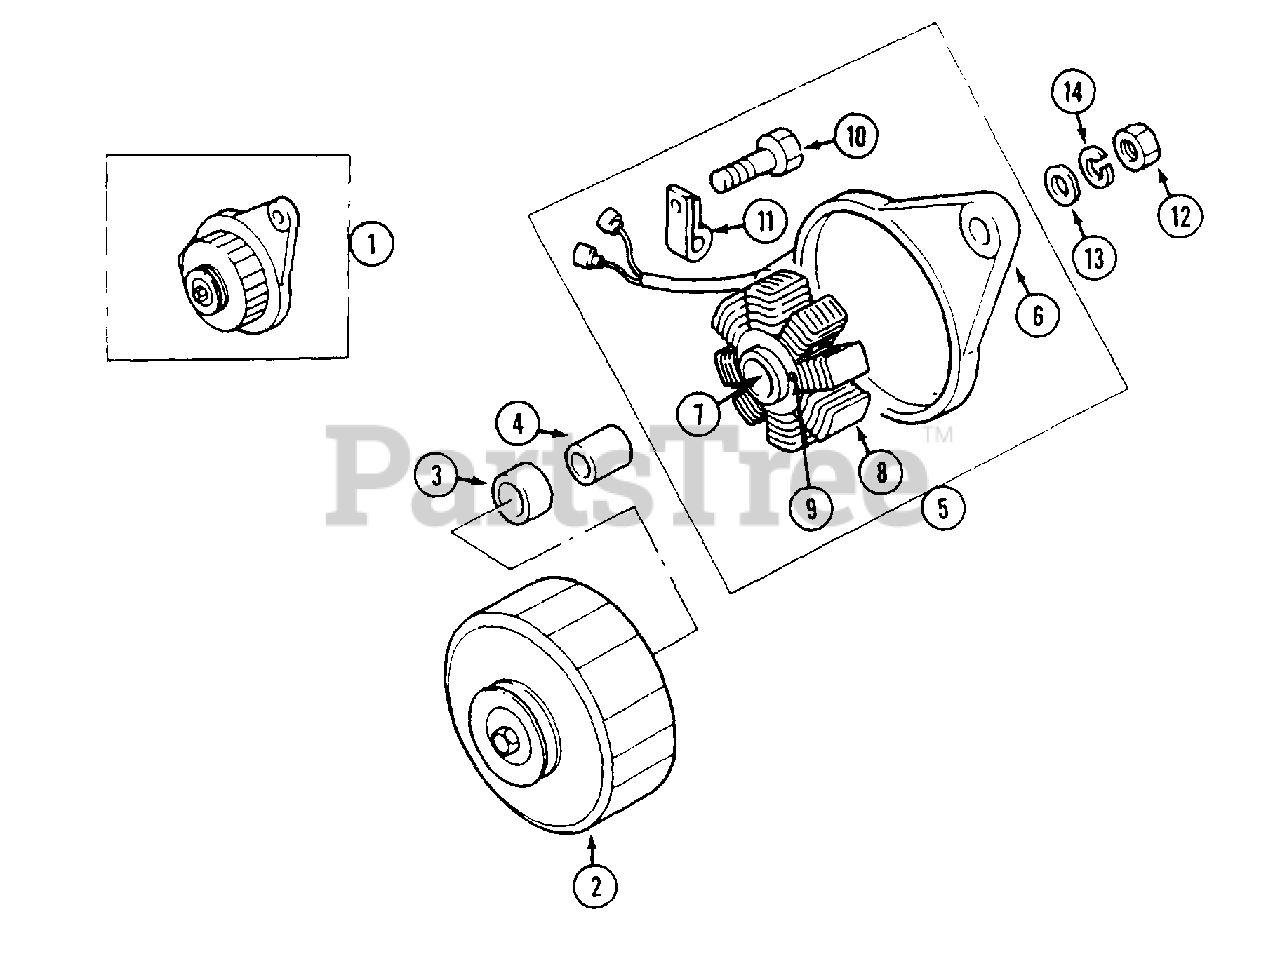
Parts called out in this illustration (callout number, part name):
1	ALTERNATOR
2	PULLEY
3	BEARING
4	COLLAR
5	PLATE ASSEMBLY
6	PLATE
7	BEARING
8	STATOR
9	SCREW
10	SCREW
11	CLIP
12	NUT
13	WASHER
14	WASHER
